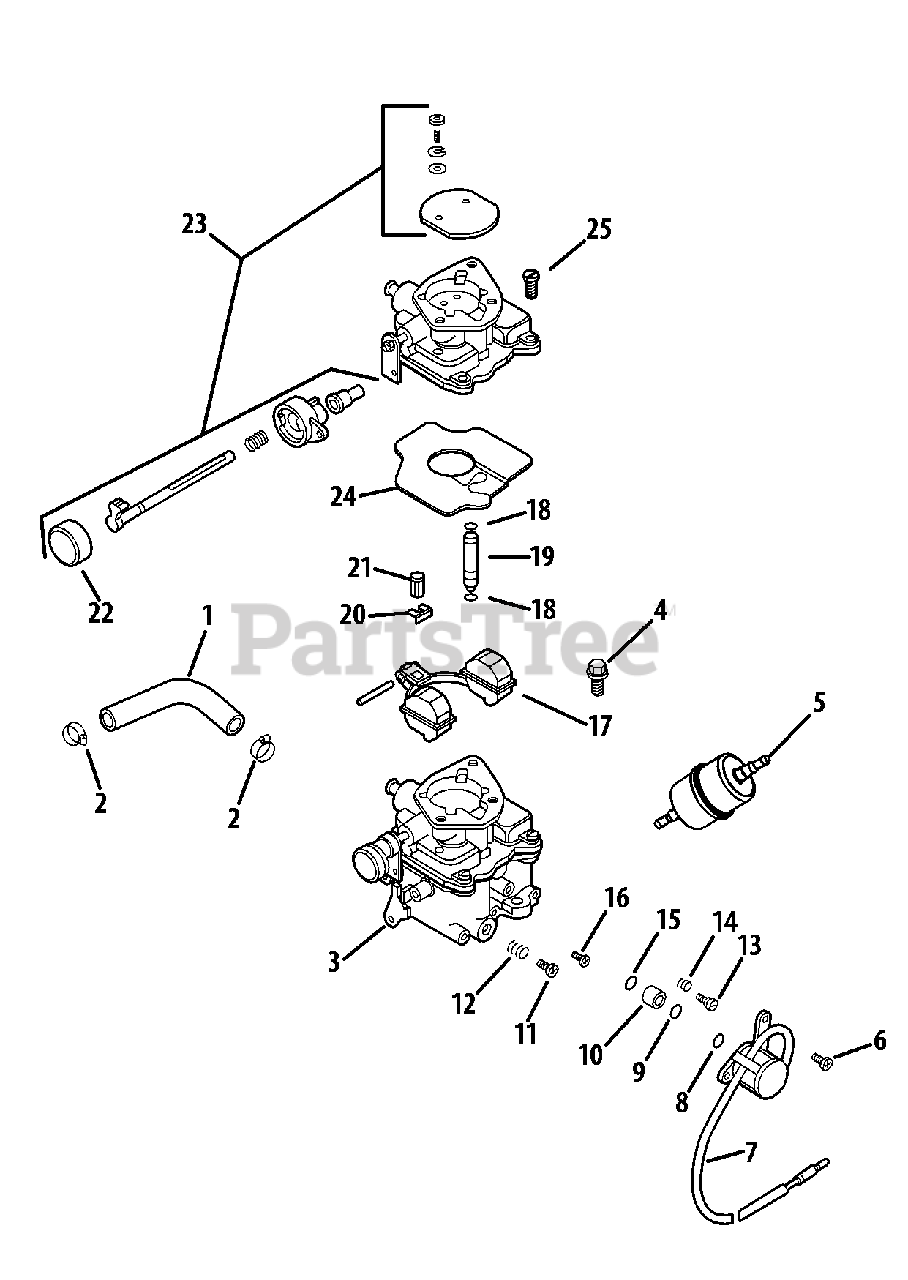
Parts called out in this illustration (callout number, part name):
1	Low Permeation Fuel Hose, 24"
2	Hose Clamp (KM)
3	Carburetor Kit w/ Gaskets
4	Flange Screw, M6 x 1.0 x 25
5	Fuel Filter
6	Solenoid Screw
7	Solenoid Assembly
8	Solenoid O-Ring
9	Solenoid O-Ring
10	Solenoid Seat
12	Idle Speed Adjustment Screw Spring
14	Idle Needle Spring
15	Solenoid O-Ring
15	Main Jet Screw O-Ring
17	Repair Float Kit
18	Slow Jet O-Ring
19	Slow Jet (Disc.)
20	Inlet Needle Valve Clip
21	Inlet Needle Valve
22	Choke Lever Cap
23	Repair Choke Kit
24	Carburetor Body Gasket
25	Carburetor Body Screw
